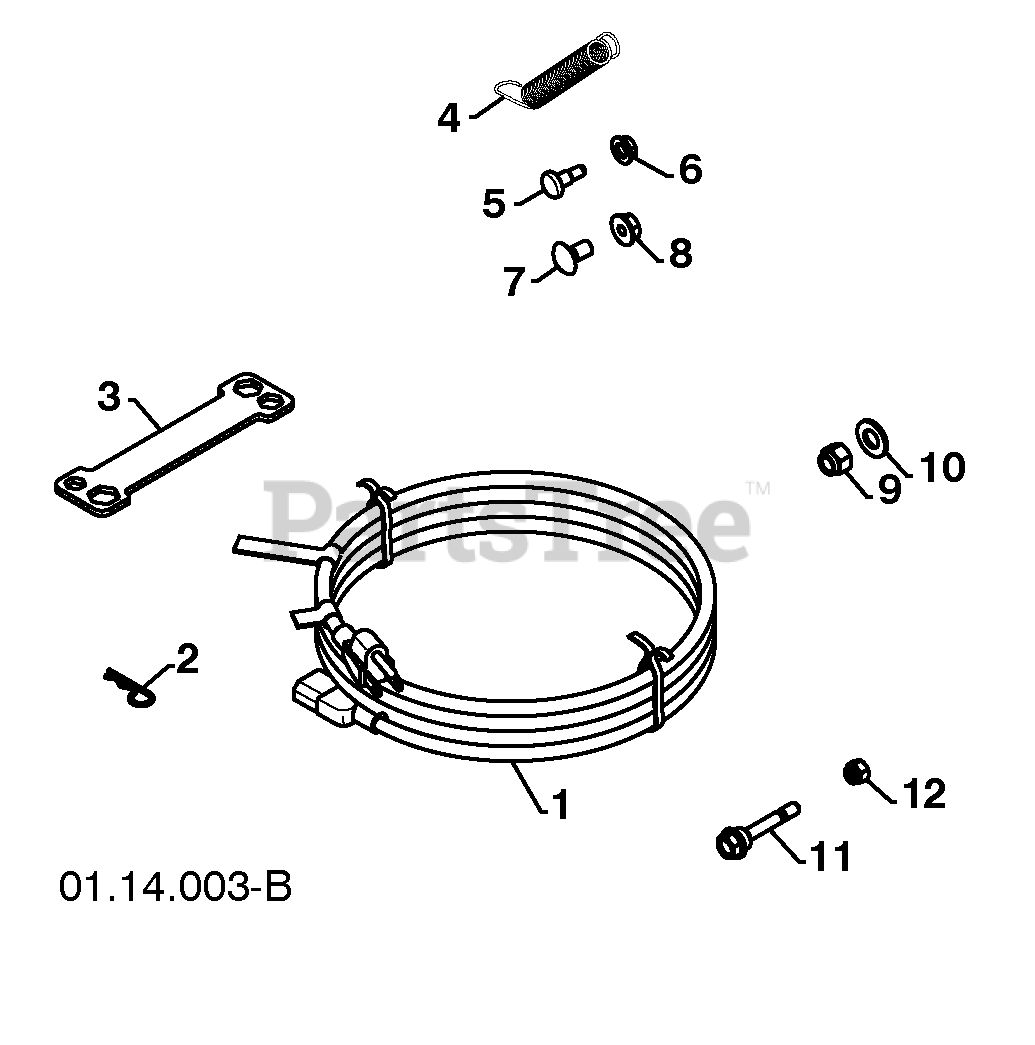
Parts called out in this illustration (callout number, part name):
1	POWER CORD
2	RETAINER PIN
4	REMOTE SPRING
5	SHOULDER BOLT 1/4-20
6	LOCKNUT 1/4-20
7	CARRIAGE BOLT 5/16-18 X 5/8
8	LOCKNUT 5/16-18
9	LOCKNUT 3/8-16
10	WASHER 3/8
11	SHEAR BOLT 1/4-20 X 1-13/16
12	LOCKNUT 1/4-20
